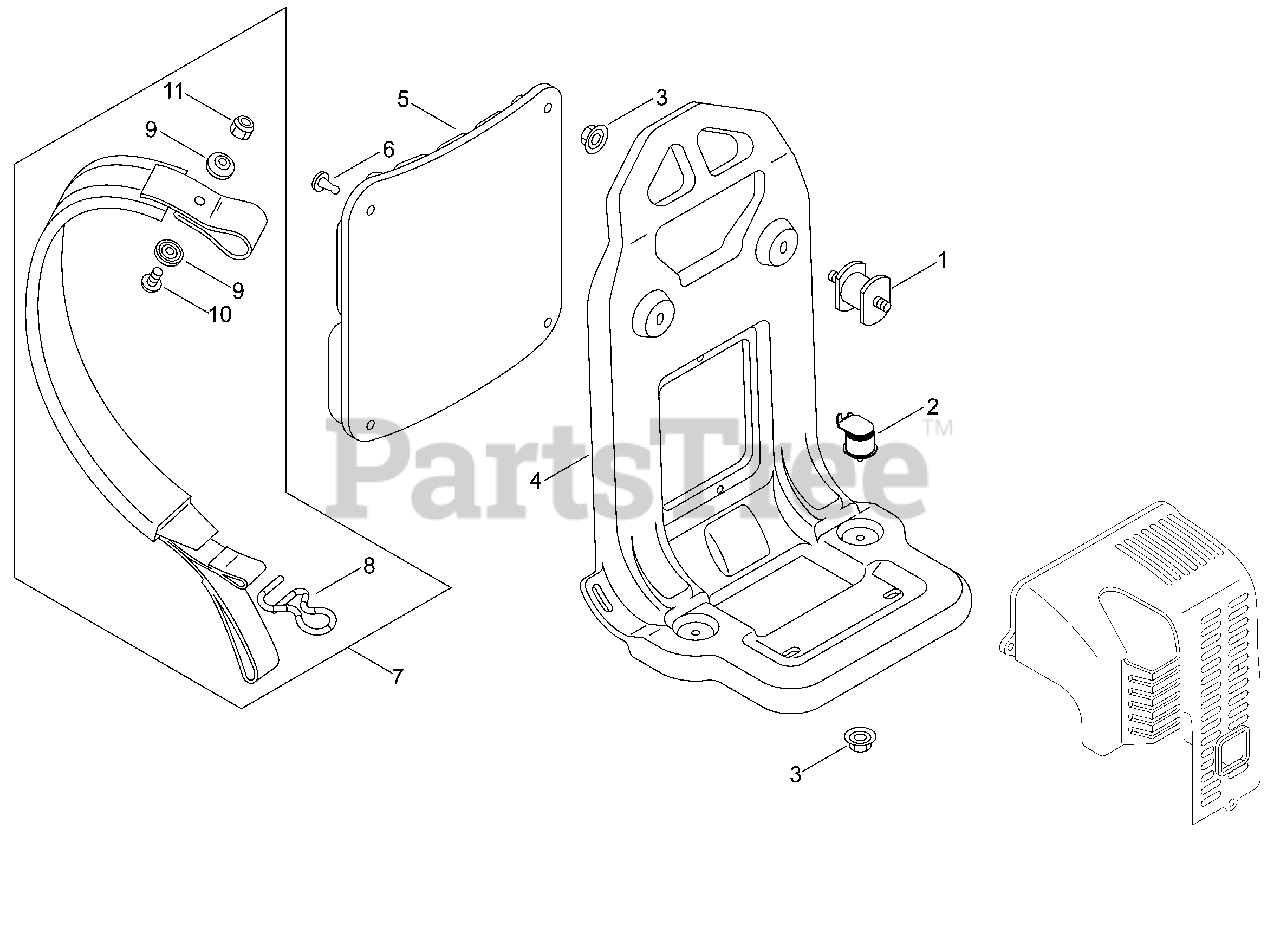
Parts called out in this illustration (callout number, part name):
1	CUSHION 6
2	CUSHION 6
4	FRAME, BACKPACK
5	CUSHION, BACKPACK
7	HARNESS ASSY, BACKPACK
8	RING, HARNESS
9	WASHER 5.2×22×2.0
10	SCREW 5×16
11	NUT, LOCK M5
